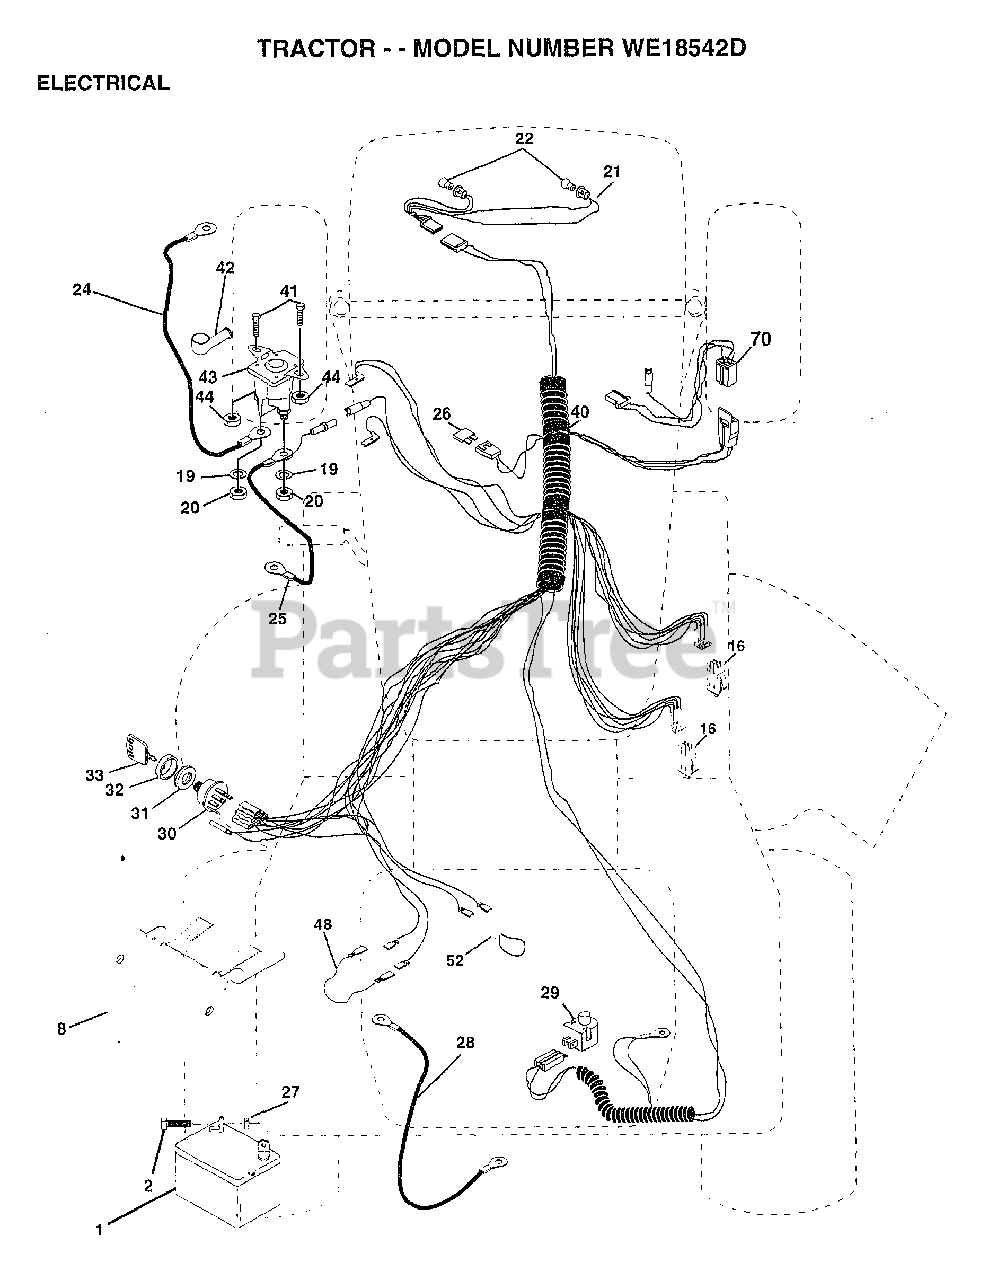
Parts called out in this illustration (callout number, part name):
2	BOLT LT
8	"CASE,BATTERY.MECH"
16	SWITCH INTERLOCK
20	NUT
21	"HARNESS,LIGHT SOC"
22	HEADLAMP BULB
24	"CABLE T, BATTERY"
25	CABLE.BTRY.6GA.RD
26	FUSE HYT
27	NUT
28	CABLE T
29	SWITCH SEAT
30	SWITCH IGN 4POS
31	NUT IGNITION
32	COVER KEY SWITCH
33	KEY
40	HARNESS-IGNITION
41	BOLT HXHD FIN
44	NUT HXKEP 1/4X20
48	ADAPTER AMMETER
52	PROTECTION LOOP
70	HARNESS ENG DUAL
